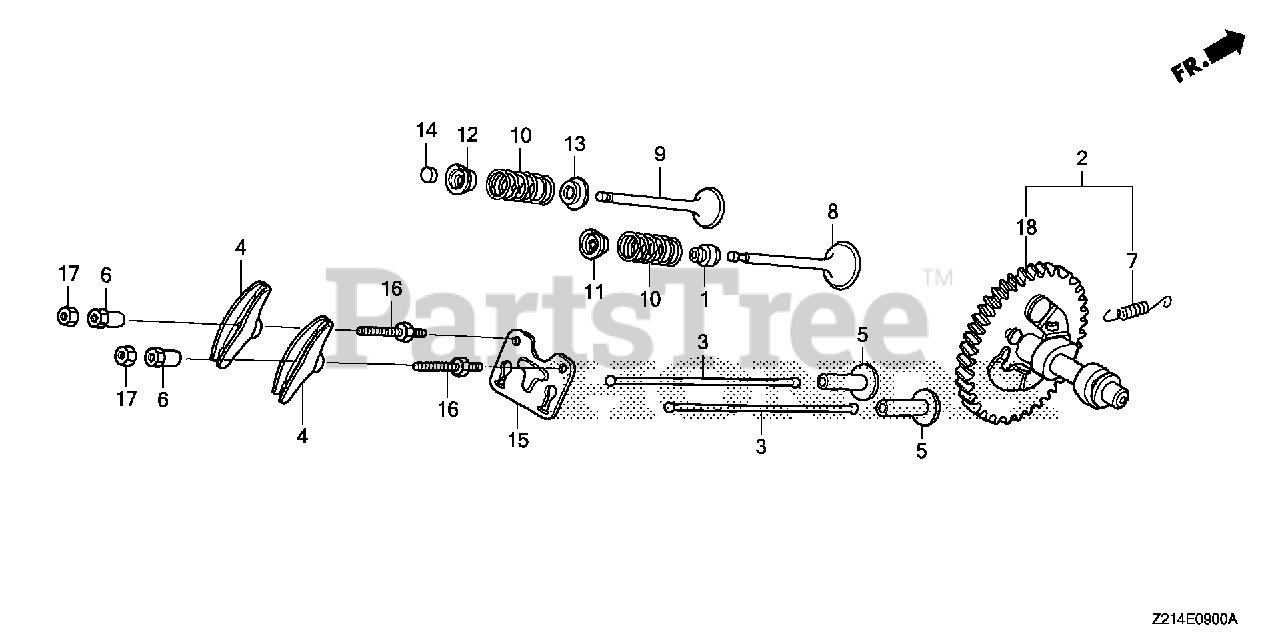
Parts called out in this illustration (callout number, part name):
1	SEAL, VALVE STEM
2	CAMSHAFT (STD)
4	ARM, VALVE ROCKER
5	LIFTER, VALVE
6	PIVOT, ROCKER ARM
7	SPRING, WEIGHT RETURN
8	VALVE, IN.
9	VALVE, EX.
10	SPRING, VALVE
11	RETAINER, IN. VALVE SPRING
12	RETAINER, IN. VALVE SPRING (EXHAUST SIDE)
13	SEAT, VALVE SPRING
15	GUIDE, PUSH ROD
16	BOLT, PIVOT (8MM)
17	NUT, PIVOT ADJUSTING
18	CAMSHAFT (STD)
